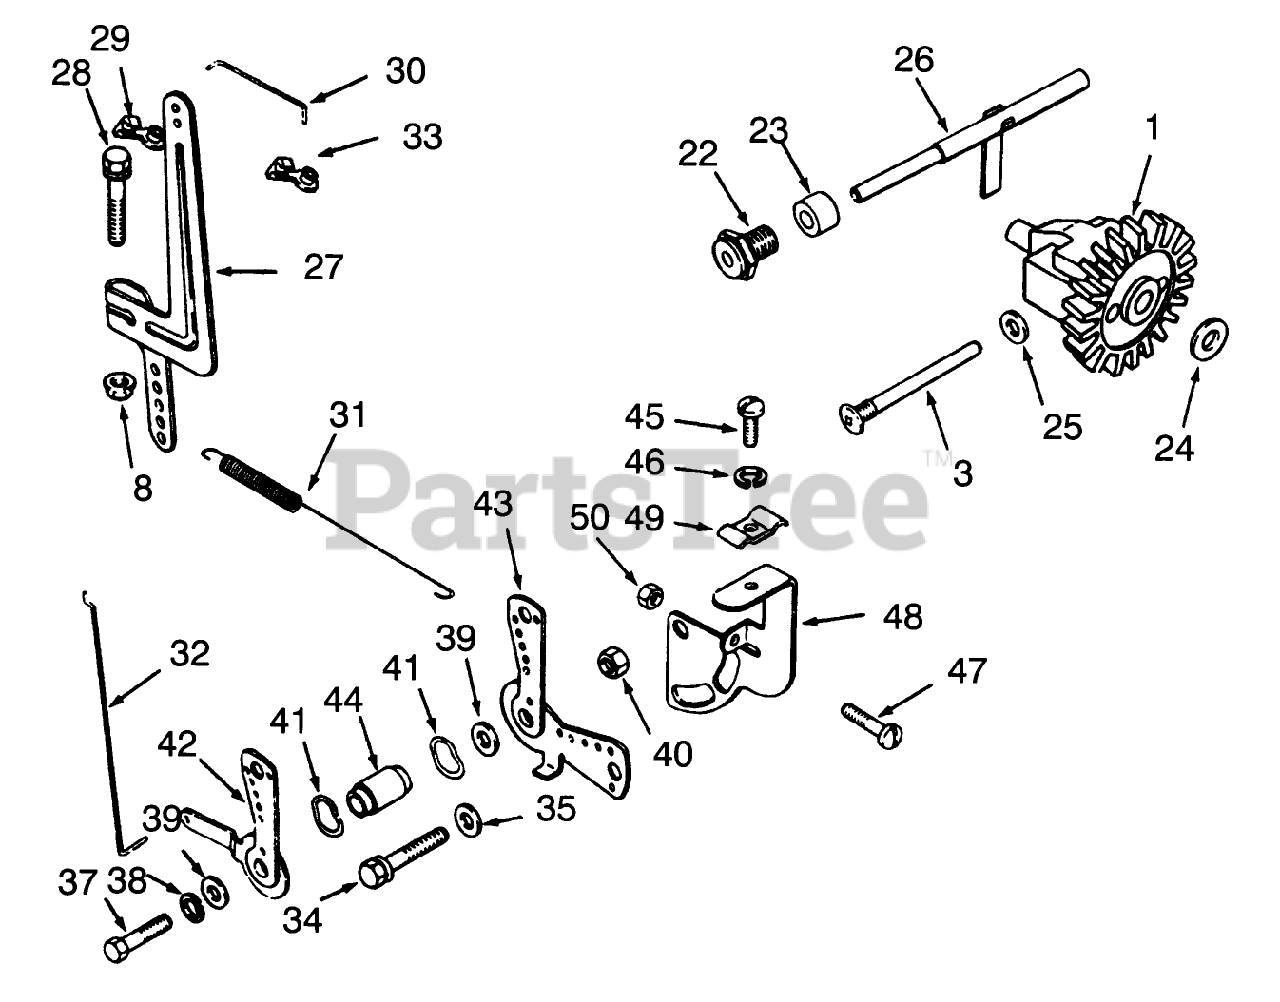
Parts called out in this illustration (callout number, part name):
1	KOHLER A-235743-5
3	KOHLER 231355
8	KOHLER X-799-1
22	KOHLER 235476
23	KOHLER X-400-80
24	KOHLER 237022
25	KOHLER 25-468-01
26	VNDR #A-235256-S
27	KOHLER 47-090-20
28	KOHLER X-776-1
30	KOHLER 47-079-10
31	KOHLER 47-091-01
32	KOHLER 47-079-01
34	KOHLER X-132-6
35	KOHLER X-25-72
37	KOHLER X-5-26
38	KOHLER X-5-1
39	KOHLER X-25-63
40	KOHLER X-76-2
41	KOHLER 275690
42	KOHLER 47-090-07
43	KOHLER 47-090-08
44	KOHLER 47-112-02
45	KOHLER X-67-51
46	KOHLER 25-468-04
47	KOHLER 232556
48	KOHLER 47-126-09
49	KOHLER 47-237-02
50	KOHLER X-72-4
